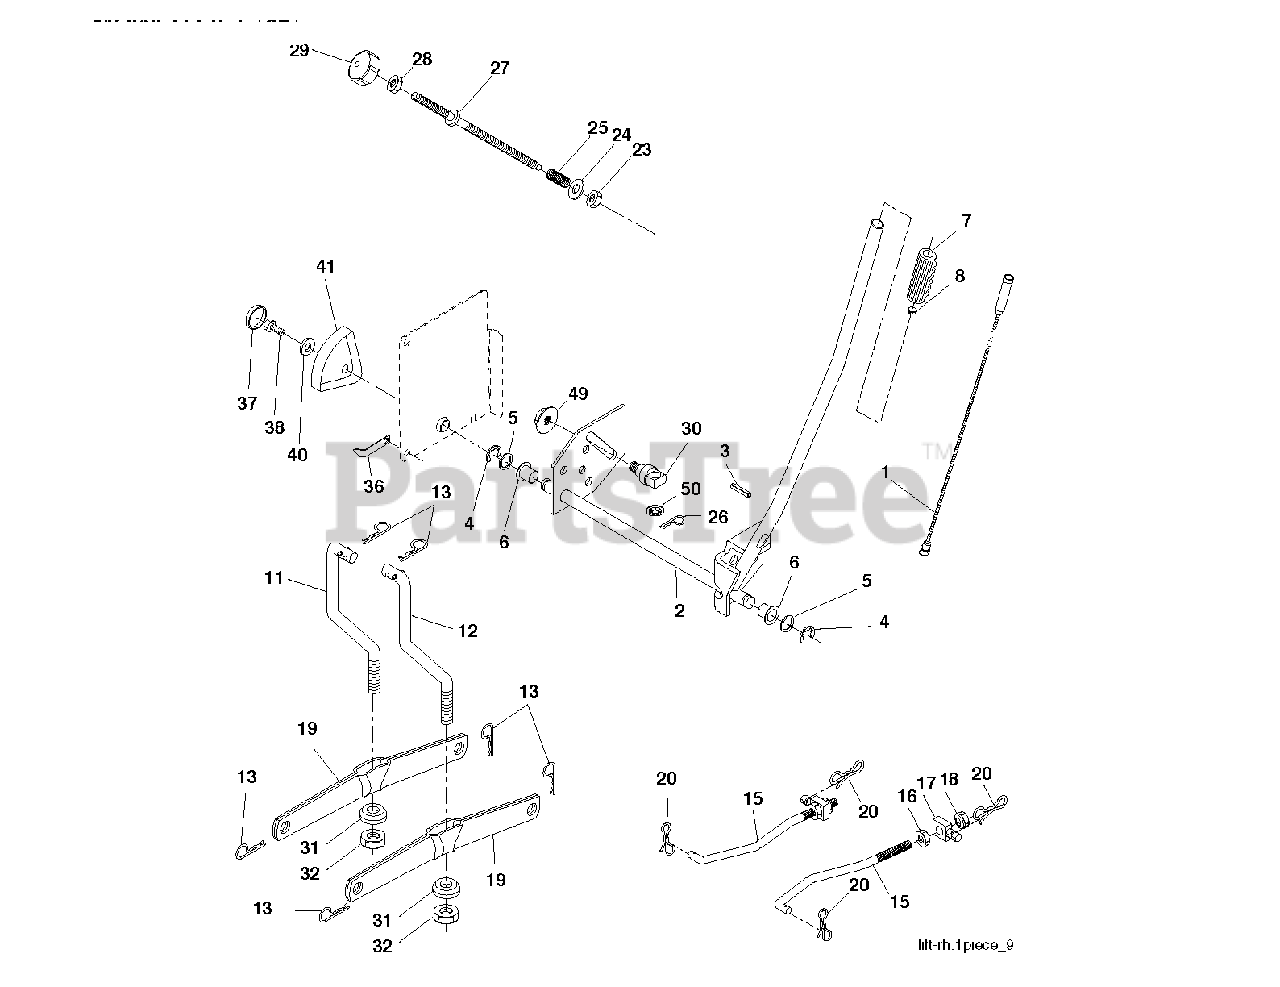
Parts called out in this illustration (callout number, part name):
1	PLUNGER.ASM.LIFT.LVR.BLK.17.32
2	SHAFT ASM R HANDLE
3	PIN GROOVE
4	RETAINING RING LT
6	BEARING.NYLON
7	GRIP HANDLE
8	PLUNGER BUT KIT
11	LINK
12	LINK
13	RETAINER-SPRNG RB
15	LINK.SUSPENSION.FRONT
16	NUT
18	NUT
19	ARM.REAR.SUSPENSION
20	PIN.COTTER.7/16.BOW TI
25	SPRING**
26	RETAINER CLIP
27	ROD ADJ LIFT
28	NUT
29	KNOB INF 3/8-16
31	BEARING.PIVOT.LIFT
32	NUT CROWNLOCK 3/8-24
36	POINTER, HEIGHT INDICATOR
37	PLUG,HOLE
38	SCREW 5/16-18X1
41	HEIGHT INDICATOR
49	NUT
50	NUT PUSH M
